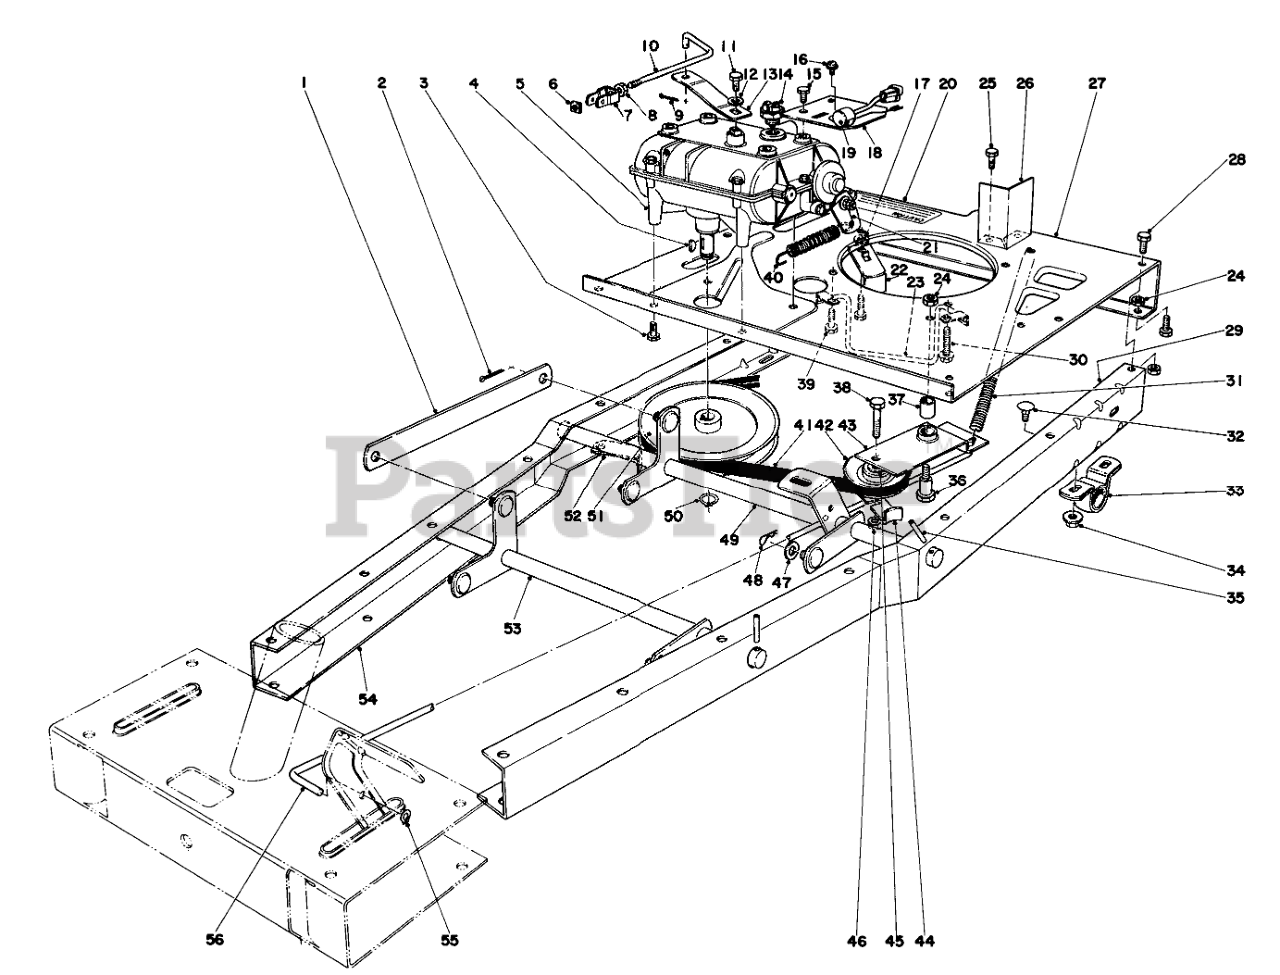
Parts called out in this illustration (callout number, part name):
1	Linkage-Height Adj.
2	PIN-COTTER
3	5/16-18 X 5/8 SEMS SC
4	KEY-WOODRUFF
5	Transmission
6	Nut-Square
7	Bracket-Rod Support
8	NUT-HEX, SIDE DEFORM
9	PIN-COTTER
11	SCREW-HH
12	WASHER-LOCK
13	Linkage-Transmission
14	SWITCH
15	SCREW-HHF
16	10-16 X 3/8 THDG SCREW
17	WASHER-PLAIN
18	Bracket-Charge Plug
19	Control Module
20	Decal
21	Spring-Brake Return
22	Belt Retainer
23	Belt Guide
24	NUT-LOCK, CONE
25	SCREW-HH
26	Baffle-Carb
27	Engine Mounting Plate
28	SCREW-HH
29	Frame Chanel, L.H.
30	SCREW-HWHTF
31	Clutch Tension Spring
32	SCREW-CARR
33	PILLOW BLOCK
34	NUT-HF
35	PIN-ROLL, SLOTTED
36	CLUTCH PIVOT BOLT
37	BUSHING
38	SCREW-HH
39	Sems Screw
40	Spring Brake
41	V-BELT
42	PULLEY-IDLER
43	Traction Idler (Incl. Ref. No. 37)
44	RETAINER-BELT
45	Washer
46	NUT-LOCK, CONE
47	WASHER-FLAT
48	PIN-COTTER
49	Height Adjustment
50	RING-SNAP, EXTERNAL
51	PULLEY
52	TRANS BELT RET B
53	FRONT LIFT WA B
54	Frame Channel R.H.
55	Retaining Ring
56	CLUTCH ROD
